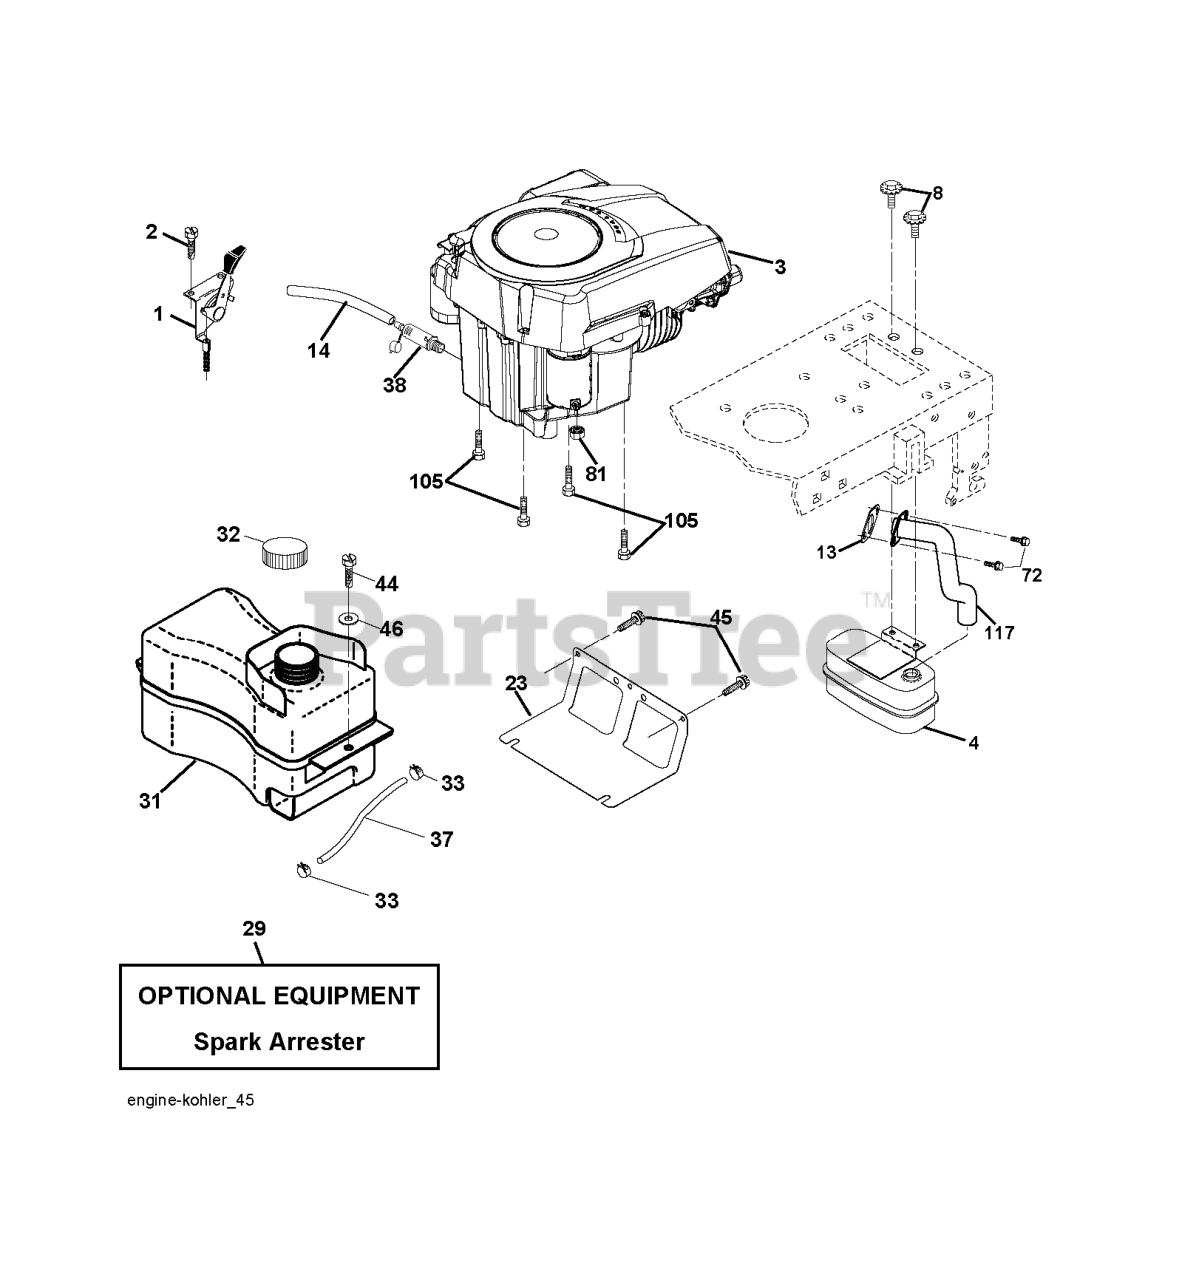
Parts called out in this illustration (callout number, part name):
1	CONTROL.TH/CK.C.
4	MUFFLER.SINGLE.CYL.KOHL/B&S
8	BOLT.5/16-18UNCX3/4 W/SEMS.BLK
13	GASKET.EXHAUST.KOHLER
14	TUBE, DRAIN OIL ASM.
23	SHIELD.BROWNING.DBR.GUARD
29	KIT.SPARK ARRESTOR 794945 B&S
31	RP TANK FUEL FRT 1.5 GAL
32	FUEL CAP
33	HOSE CLAMP
37	LINE.FUEL.20
38	PLUG DRAIN OIL EASY
44	SCREW HEXWSHR 1/4-20X3/4
45	SCREW, 3/8-16X3/4
72	SCREW.SOCKET HD.5/16-1
81	NUT
105	SCREW 3/8-16X1
117	RP.TUBE.EXHAUST.KOHL.COURAGE
